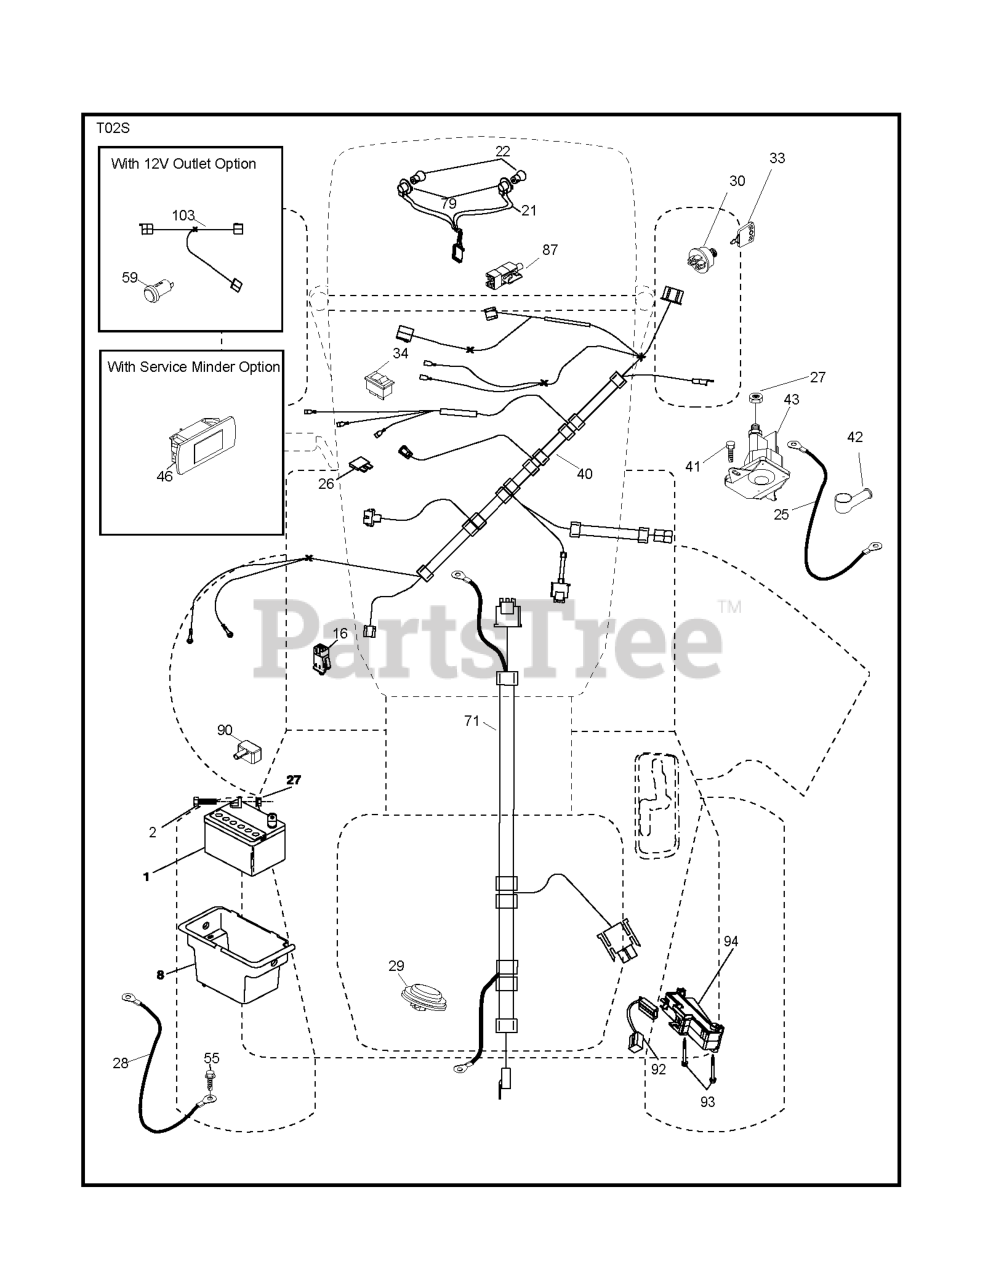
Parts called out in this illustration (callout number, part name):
1	Battery 12 Volt 25 Amp
2	BOLT.HEX.1/4.X.3/4.DICHROMATE
8	BOX.BATTERY.MNT.REAR.L
16	SWITCH INTERLOOK PUSH-IN
21	HARNESS.LIGHT W/4152J BULBS
25	CABLE.STARTER.6GA.BL/RED.14.
26	FUSE 20AMP
27	NUT
28	CABLE.BLACK.18"REAR.BA
29	SWITCH.SEAT.DELTA.OPC.
30	SWITCH.IGN.DELTA.W.LGH.ROS
33	KEY.CHAIN.BLISTER.PACK.GEN.USA
40	HARNESS IGN. DASH
41	SCREW
42	TERMINAL COVER
43	SOLENOID.W/BRASS.PLUNGER
46	RP.GUAGE.SRVCMNDR.HRMTR.
55	SCREW 5/16"
71	HARNESS.IGN.CHASS.TEX.REAR.BAT
79	BULB HOLDER ASM.
87	SWITCH.INTRLCK.CLUTCH.
90	COVER, TERMINAL BATTERY
92	HARNESS.PIGTAIL.CONSLE
93	SCREW.PLASTITE
94	MODULE.REVERSE.ROS
